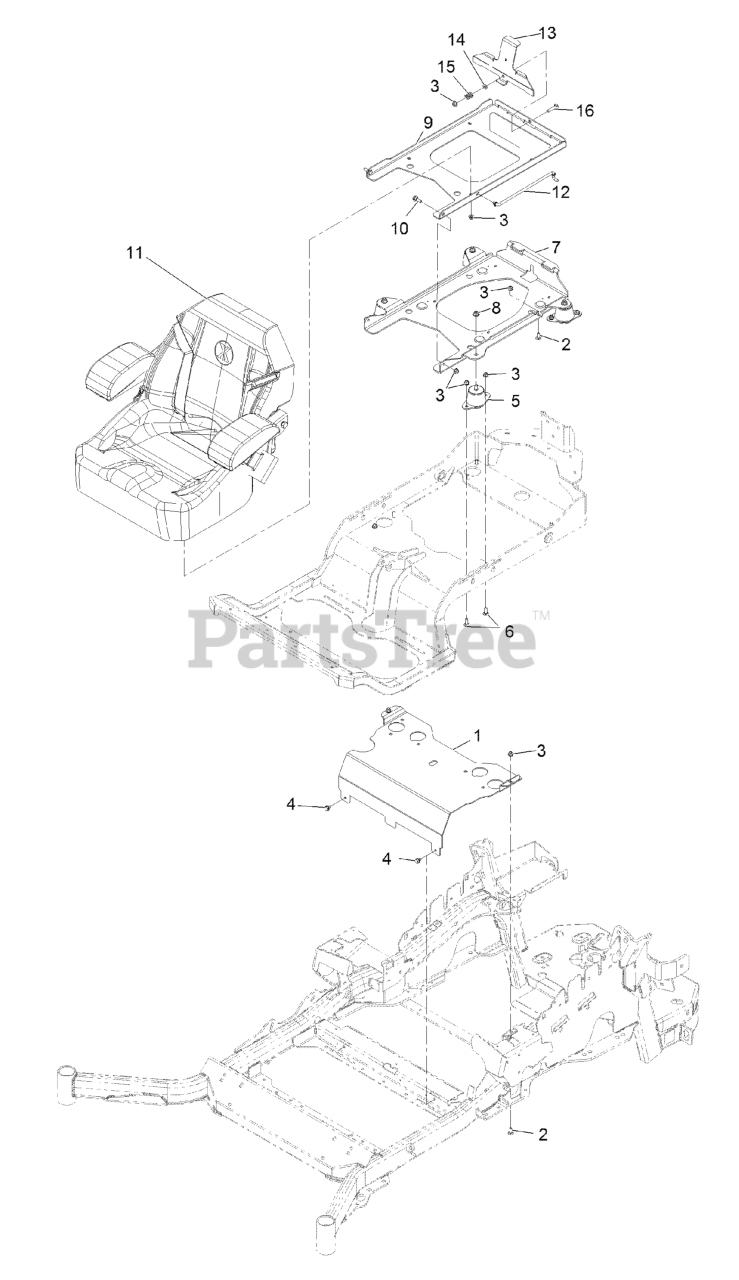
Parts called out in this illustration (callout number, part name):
1	Panel-Front, Seat Mount
2	SCREW-CARR
3	NUT-HF, NI
5	ISOLATOR-SEAT
6	BOLT-CARR
7	PLATE-SUPPORT, ISO SEAT
8	NUT-HF, NI
9	PLATE-FRAME, SEAT
10	SCREW-SHOULDER
11	SEAT-EXMARK STANDARD
12	ROD-PROP
13	PLATE-LATCH,SEAT
14	WASHER-PLAIN
15	SPRING-COMPRESSION
16	BOLT-CARR
